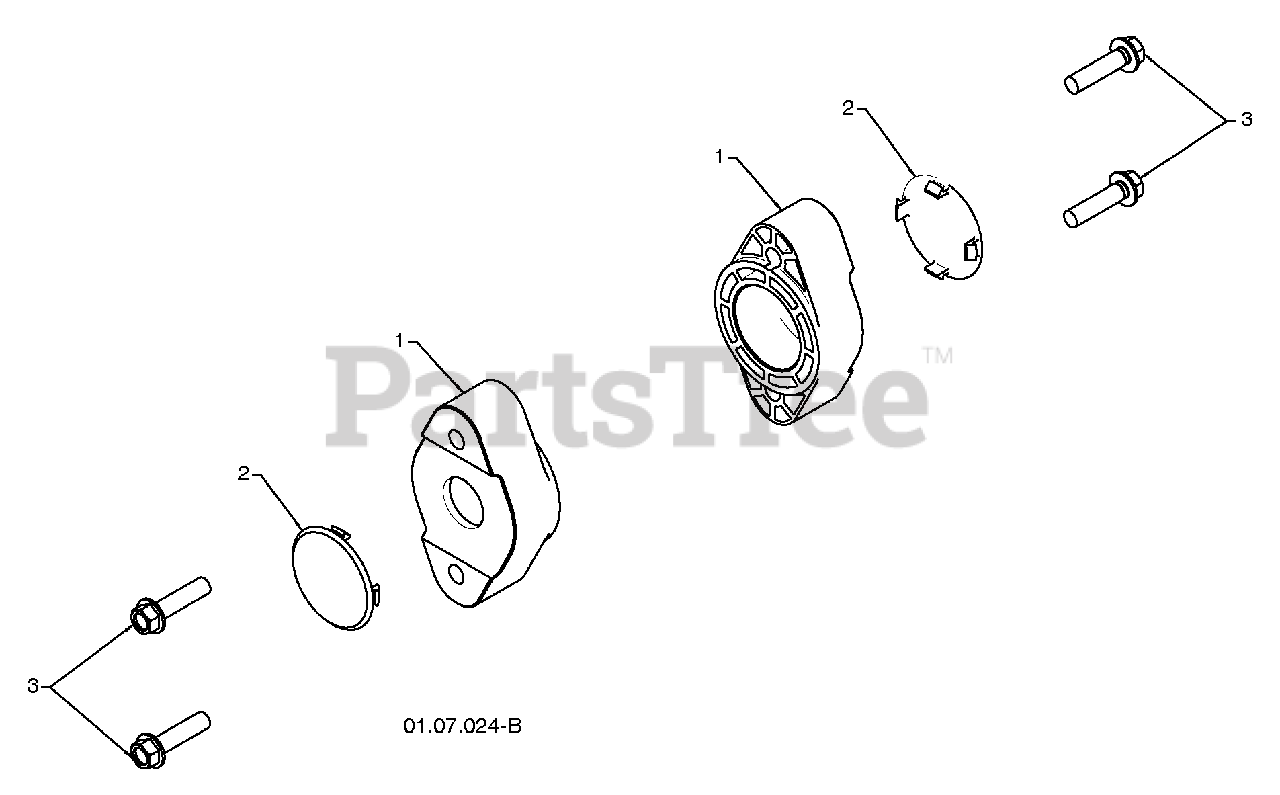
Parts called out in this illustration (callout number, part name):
1	AUGER BEARING
2	BEARING PLUG
3	SCREW 5/16-18 X 1.00
